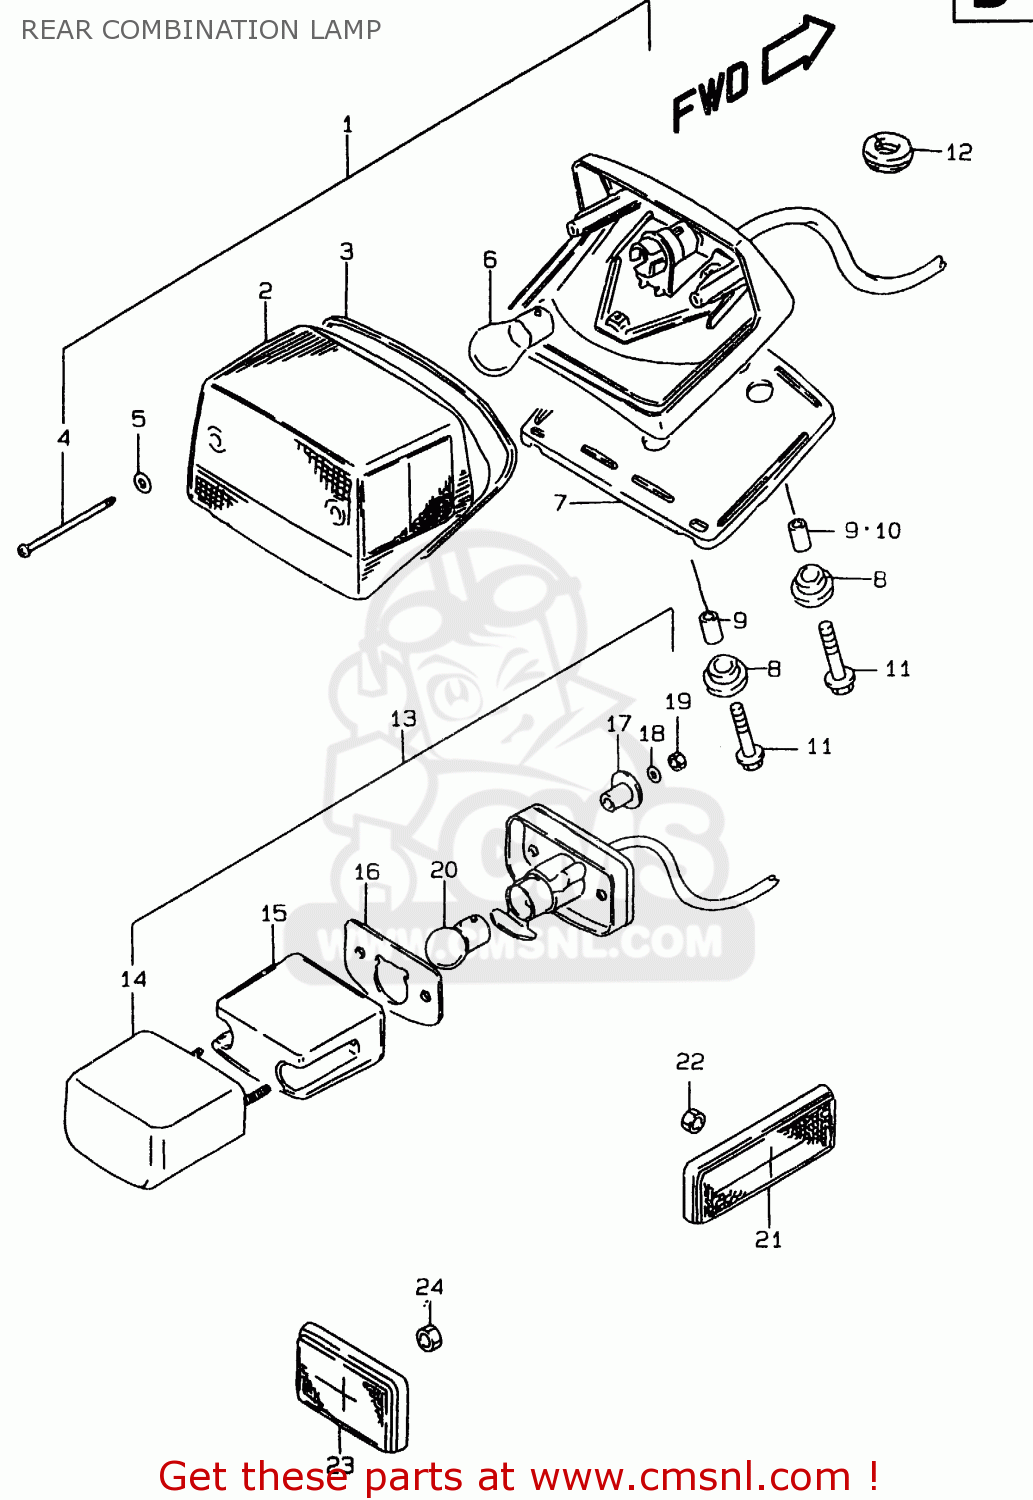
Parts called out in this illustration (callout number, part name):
1	LAMP ASSY,RR COMBINATION
2	LENS
3	GASKET (NAS)
4	SCREW
5	GASKET (NAS)
6	BULB(12V21/5W)
7	CUSHION
8	CUSHION
9	SPACER
10	SPACER
11	BOLT(6X25)
12	GROMMET
13	LAMP ASSY,LICENSE
14	COVER,LICENSE LAMP
15	LENS
16	GASKET,LICENSE LAMP (NAS)
17	SPACER
18	WASHER,LOCK
19	NUT
20	BULB(12V5W,BF150-40160A)
21	REFLEX REFLECTOR,FR SIDE
22	NUT
23	REFLEX REFLECTOR ASSY,RR
24	NUT
